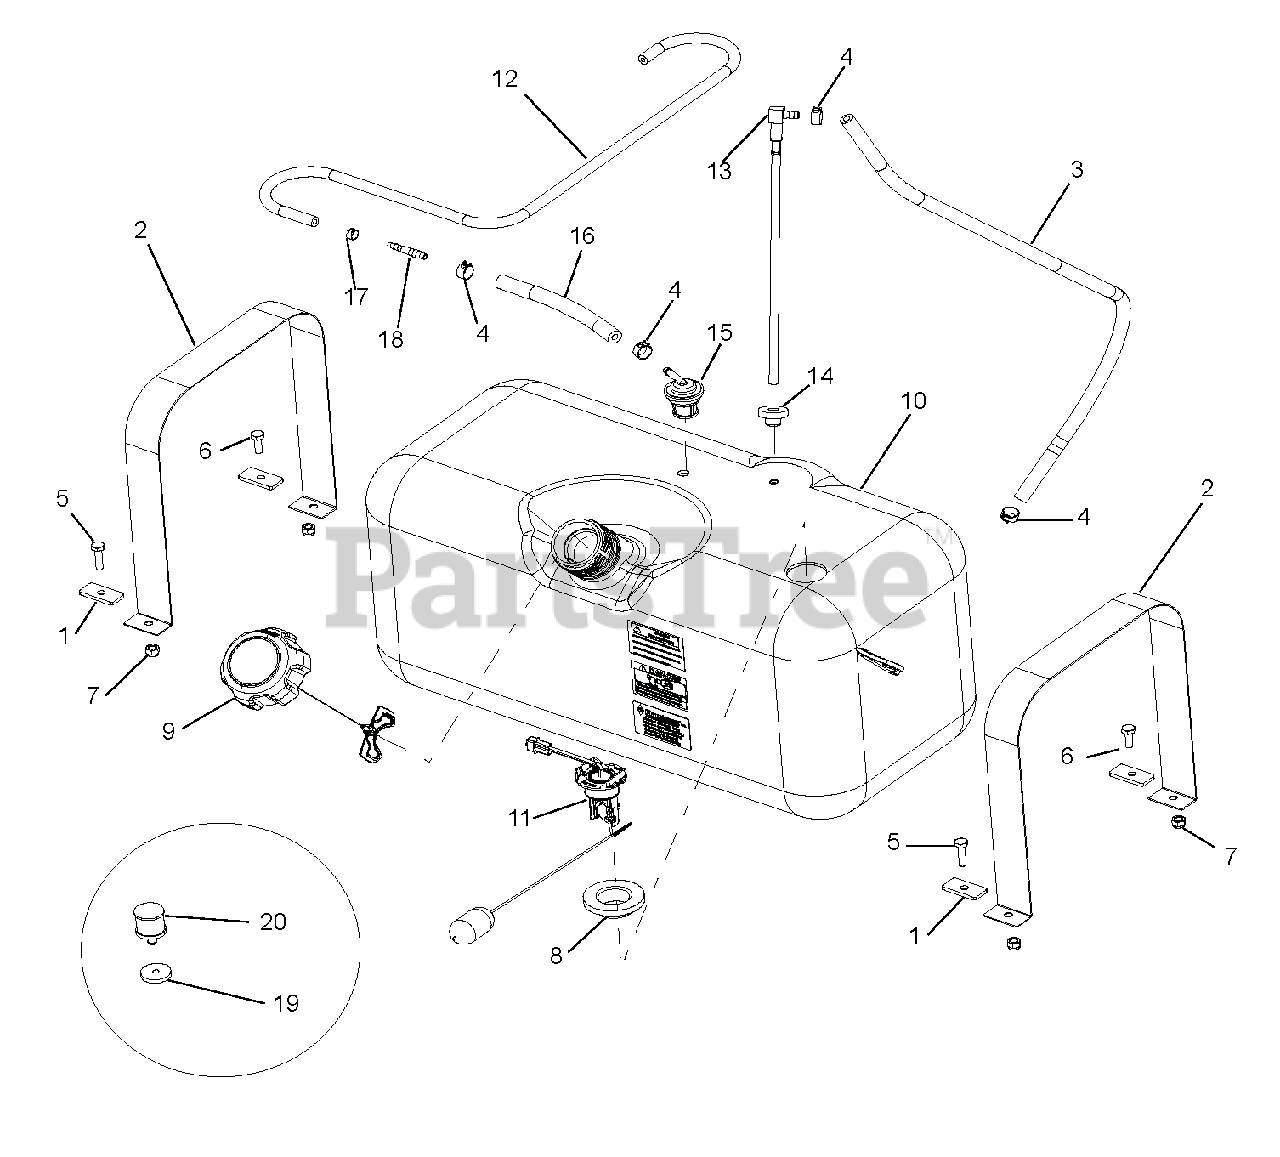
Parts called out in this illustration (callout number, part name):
1	GAS TANK MOUNT SPACER
2	GAS TANK STRAP, WIDE
3	FUEL LINE 10" ST MODEL
4	CLAMP, FUEL LINE
5	@BLT-HEX .25-20X.75 GR5 YWZC
6	@BLT-HEX .25-20X1.00 GR5 YWZC
7	@NUT-LK-NYL .250-20 YWZC
8	GROMMET, FUEL SENDER
9	CAP, FUEL VENT-IN 2.25" RATCH.
10	TANK, FUEL 2012 EPA
11	SENDER, FUEL LEVEL
12	HOSE, .188 LOW-PERM BULK GAS
13	FUEL, TANK PICK-UP LINE
14	GROMMET, DAPCO VITON #12240
15	VALVE, GROMMET FUEL TANK VENT
16	HOSE, .25 LOW-PERM BULK GAS
17	CLAMP-HOSE, SPRING .188
18	ADAPTOR, HOSE 3/16 TO 1/4
19	GROMMET, FUEL TANK
20	SLOSH VALVE, FLAMBEAU 468885A
